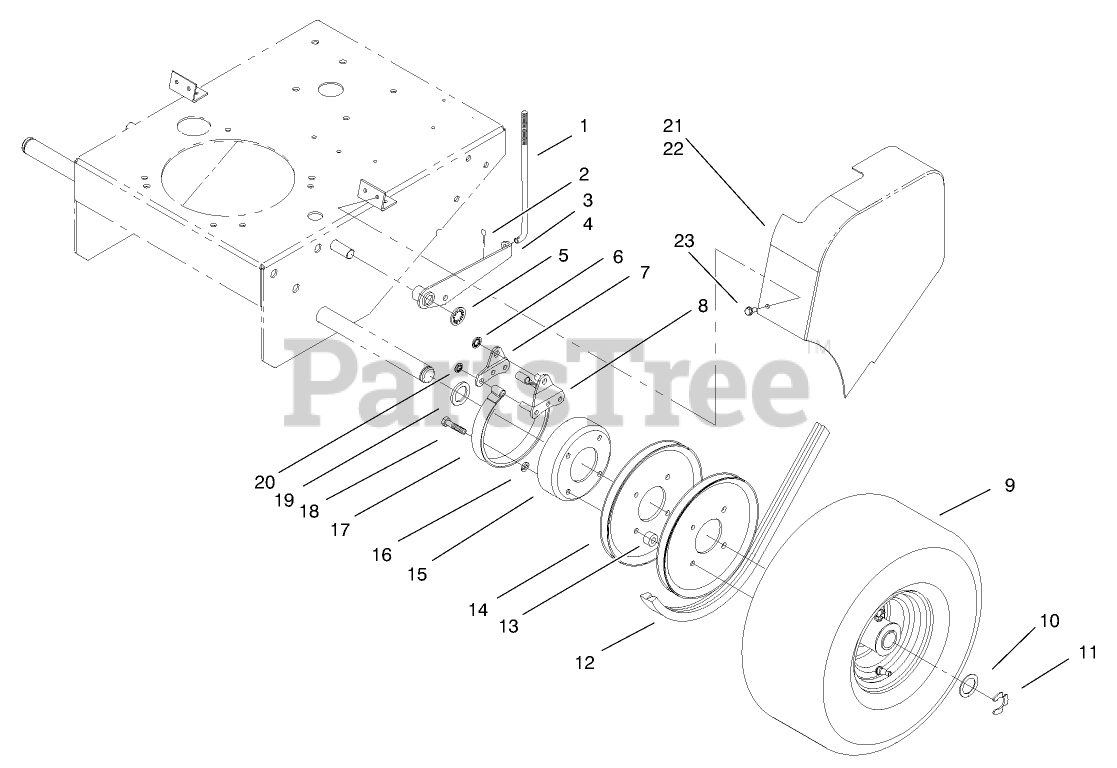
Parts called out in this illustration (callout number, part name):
1	ROD-BRAKE
2	PIN-COTTER
3	ARM-BRAKE, RH
4	ARM-BRAKE, LH
5	RING-RETAINING
6	RING-RETAINING, EXTERNAL
7	PLATE-LINK, BRAKE
8	LINK-BRAKE
9	WHEEL AND TIRE ASM
10	WASHER-THRUST
11	RING-RETAINING
12	V-BELT
13	SPACER-PULLEY
14	PULLEY-WHEEL
15	DRUM-BRAKE
16	WASHER-LOCK
17	BAND-BRAKE
18	SCREW-HH
19	WASHER-WHEEL
20	RING-RETAINING
21	GUARD - RH BELT
22	GUARD - LH BELT
23	SCREW
